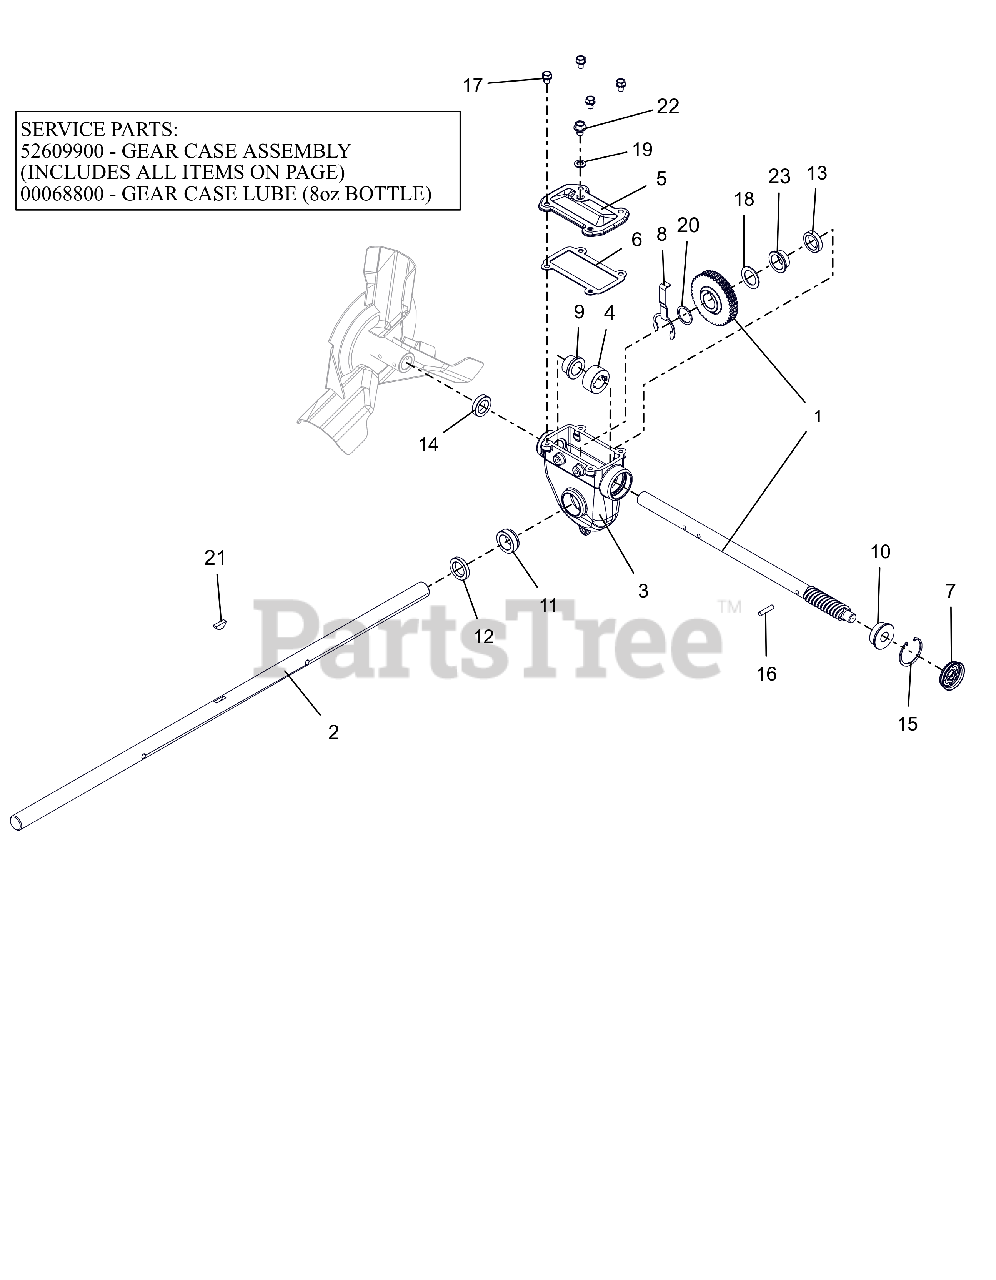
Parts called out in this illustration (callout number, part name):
1	ASSY, WORM SHAFT & GEAR
2	SHAFT, RAKE-36"
3	GEARCASE, LARGE MACHINED
3	GEAR CASE, 36" IRON PRO TOP-LD
4	THRUST COLLAR, .875"ID SLIPFIT
5	COVER, TOP - LARGE IRON
6	GASKET, TOP - LARGE GEARCASE
7	COVER, GEAR CASE 1.75"
8	BUSHING RETAINER, LARGE
9	BSHG-FLG .879X1.128X.75X1.45
10	BSHG-FLG .628X1.503X.58X1.725
11	BSHG-FLG LARGE, RIGHT
12	SEAL-OIL .999X1.500X.250 TBC29
13	SEAL-OIL .999X1.375X.312 TBC29
14	SEAL-OIL .873X1.375X.312 TBC29
15	RG-RTNG-INT 1.750X.062
16	PIN-STR .250X1.12 6150
17	BLT, SEMS .31-18X.50 G5 ZCC
18	WSHR, FLT 1.010X1.505X.062 ZCC
19	WSHR-BND-SEAL .38X.75X.11 GALV
20	WSHR, FLT 1.010X1.250X.068 ZCC
21	KEY-WDRF .25X.875 HRD #A
22	SCR,TAP .38-15X.50 HWH ROLOK
23	BSHG-FLG 1.006X1.128X.555X1.45
